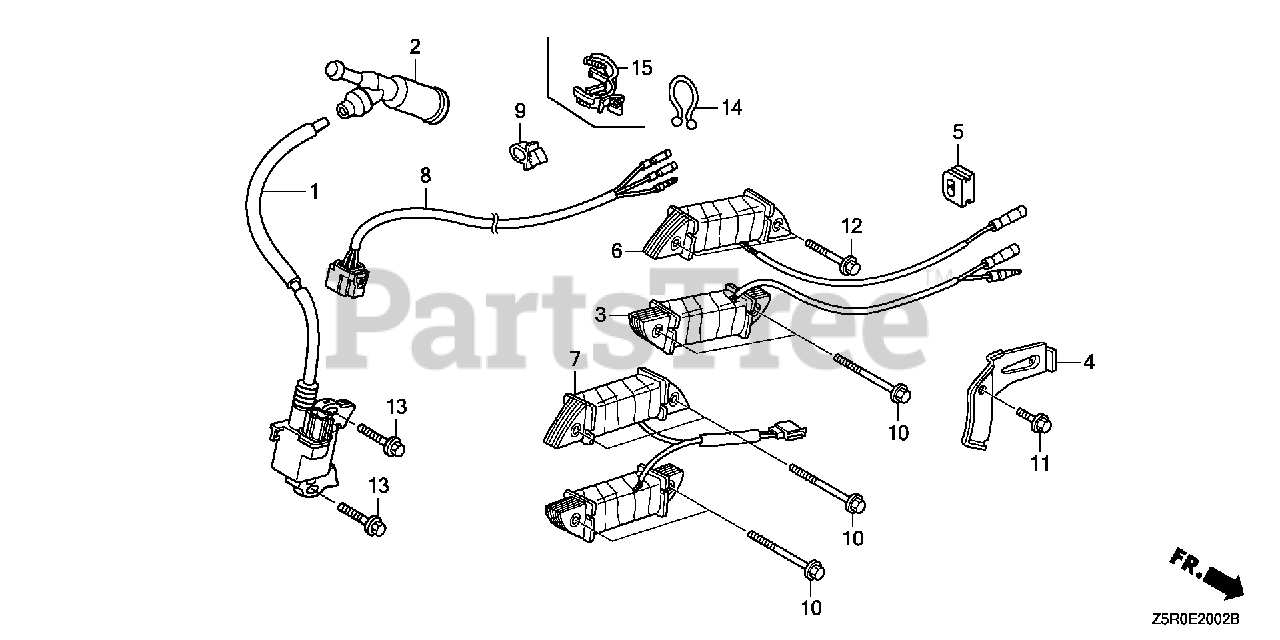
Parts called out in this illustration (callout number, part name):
1	COIL ASSY., IGNITION
2	CAP ASSY., NOISE SUPPRESSOR (NICHIWA Y-EZ RTFM256)
5	GROMMET, WIRE
8	WIRE HARNESS ASSY., ENGINE
9	HOLDER, STOP SWITCH WIRE
13	BOLT, FLANGE (6X28) (CT200)
15	CLIP, HARNESS
